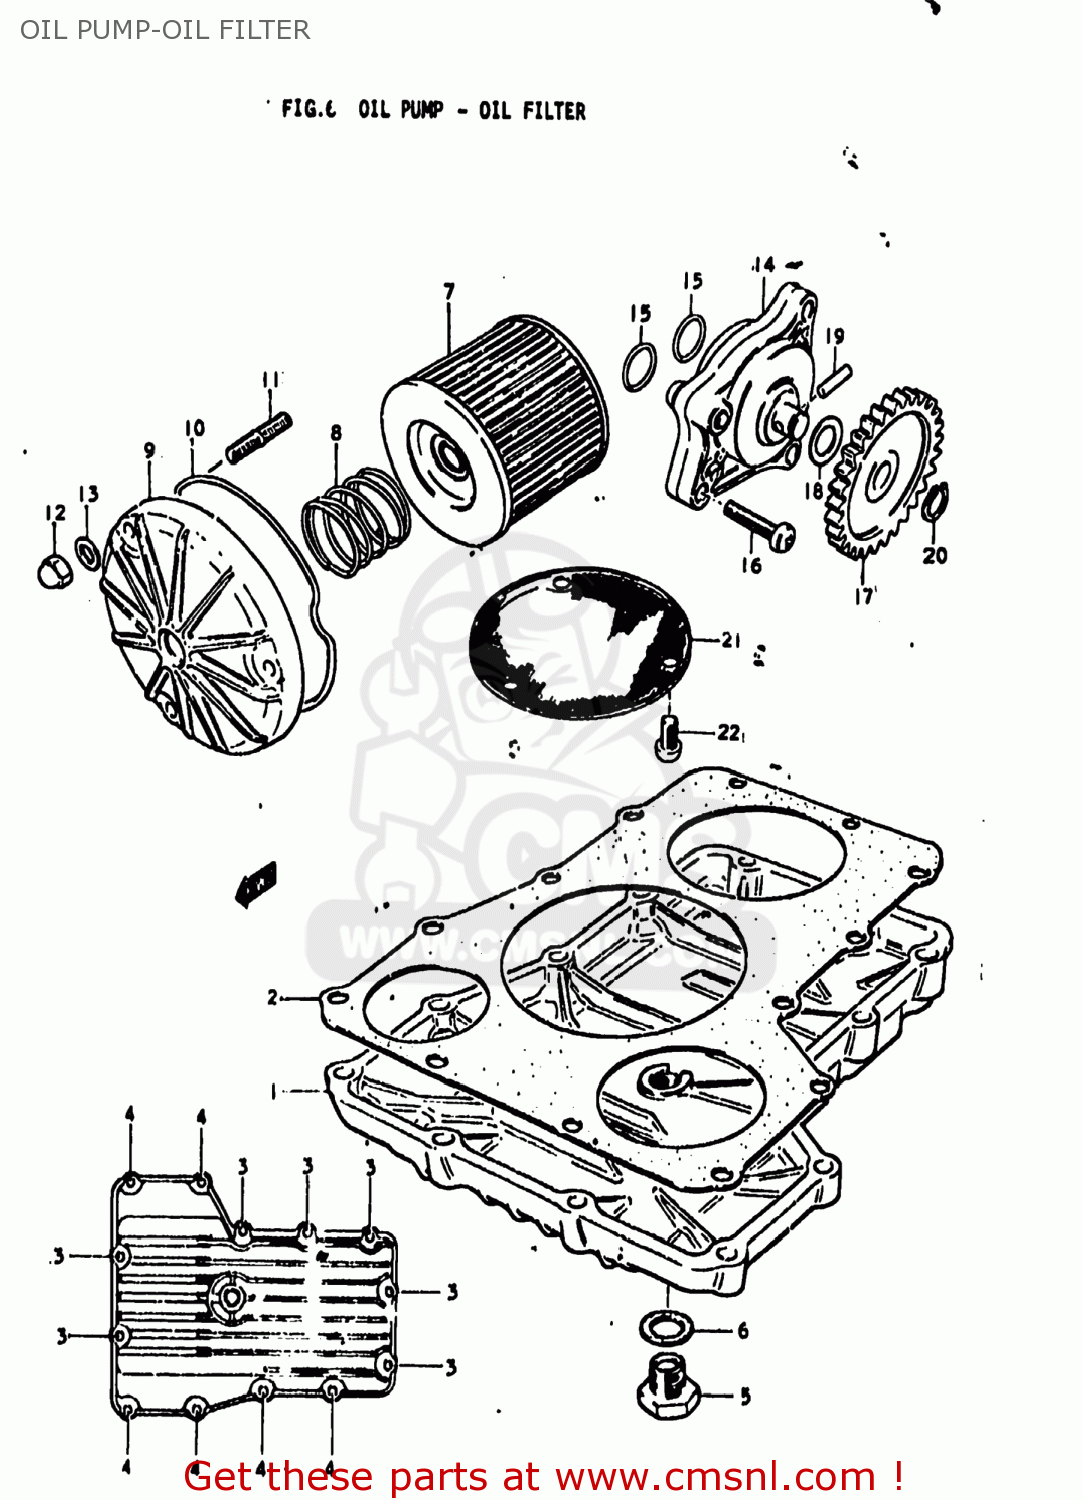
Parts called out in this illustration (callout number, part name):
1	PAN,OIL
2	GASKET,OIL PAN (MCA)
3	BOLT
4	BOLT
5	PLUG
6	GASKET(14X19.2X2) (NAS)
7	FILTER ASSY,ENGINE OIL
8	SPRING
9	CAP,OIL FILTER
10	O RING,OIL FILTER CHAMBER CAP
11	STUD 6X20
12	NUT
13	WASHER
14	PUMP ASSEMBLY,OIL
15	O RING(D:1.9,ID:13)
16	SCREW
17	GEAR,OIL PUMP DRIVEN
18	SHIM
19	PIN(4X15.8)
20	CIRCLIP
21	STRAINER,ENGINE OIL
22	SCREW 6X12
